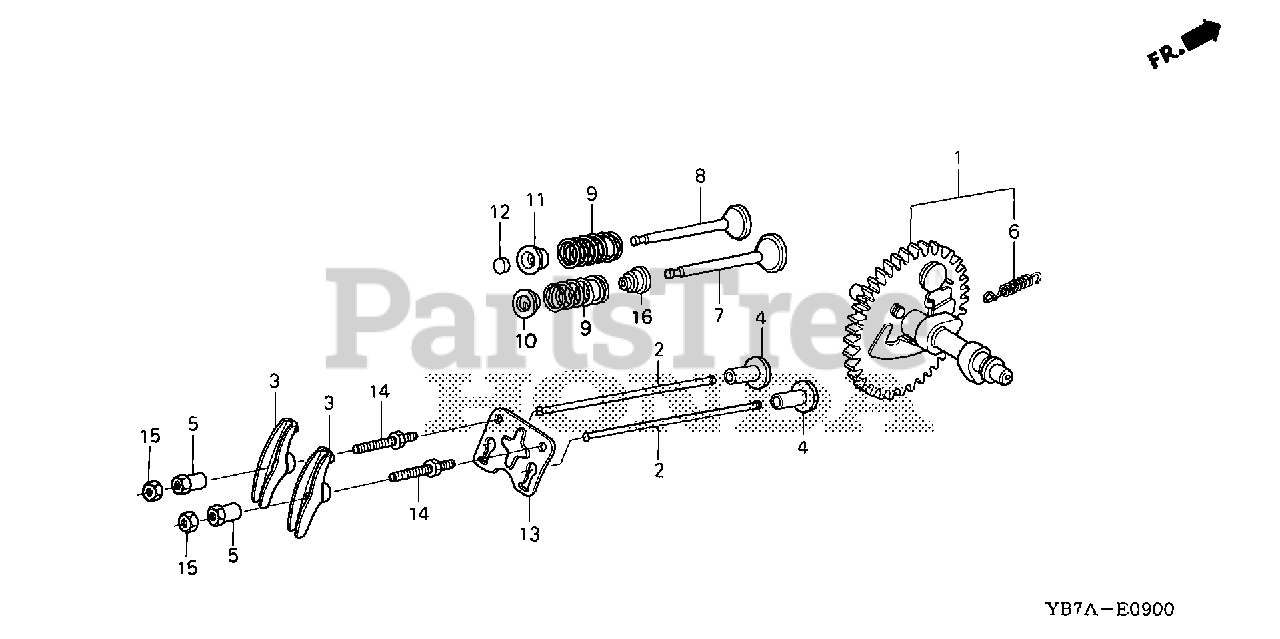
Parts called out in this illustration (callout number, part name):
1	CAMSHAFT ASSY.
3	ARM, VALVE ROCKER
4	LIFTER, VALVE
5	PIVOT, ROCKER ARM
6	SPRING, WEIGHT RETURN
7	VALVE, IN.
8	VALVE, EX.
9	SPRING, VALVE
10	RETAINER, IN. VALVE SPRING
10	RETAINER, VALVE SPRING
11	RETAINER, EX. VALVE SPRING
12	ROTATOR, VALVE
13	PLATE, PUSH ROD GUIDE
14	BOLT, PIVOT (8MM)
15	NUT, PIVOT ADJUSTING
16	SEAL, VALVE STEM
